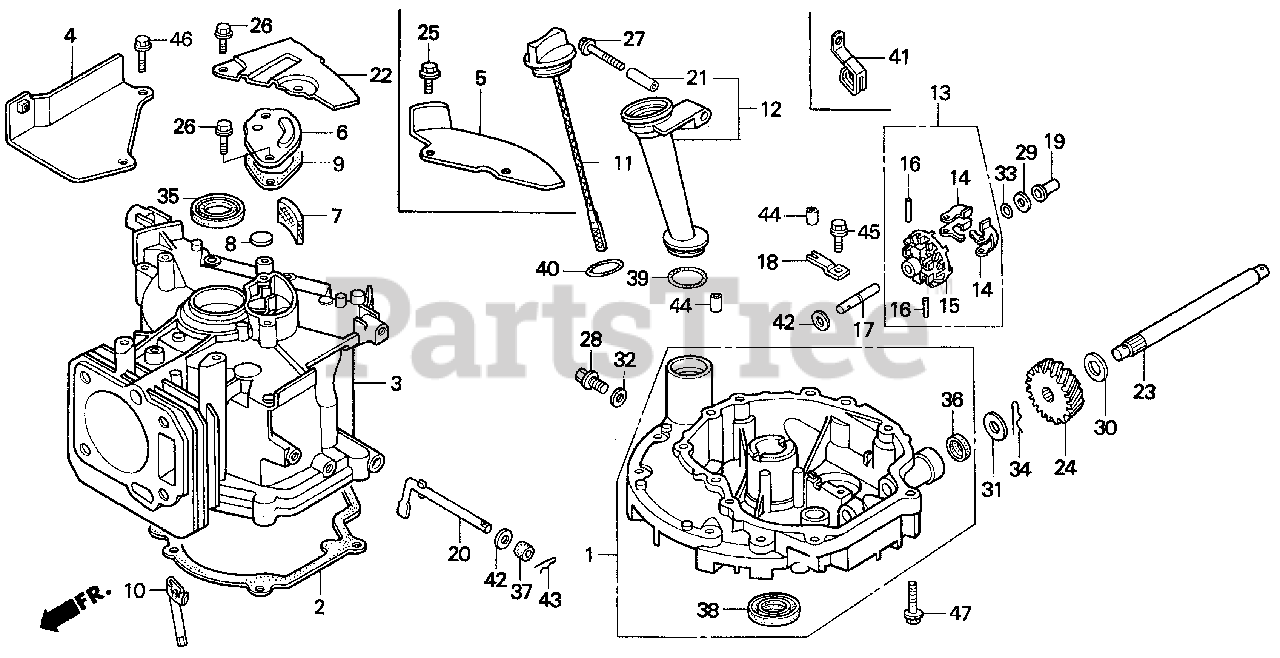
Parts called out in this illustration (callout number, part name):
1	PAN ASSY., OIL (USA-PUSH)
2	GASKET, OIL PAN
3	CYLINDER
6	CAP, BREATHER CHAMBER
7	FILTER, BREATHER
8	VALVE, BREATHER
9	GASKET, BREATHER CHAMBER
10	PIPE, OIL DEFENSE
11	DIPSTICK, OIL
12	EXTENSION, OIL FILLER
13	GOVERNOR ASSY.
14	WEIGHT, GOVERNOR
15	HOLDER, GOVERNOR WEIGHT
16	PIN, GOVERNOR WEIGHT
17	SHAFT, GOVERNOR HOLDER
18	PLATE, GOVERNOR SHAFT HOLDER
19	SLIDER, GOVERNOR
20	SHAFT, GOVERNOR ARM
21	COLLAR, EXTENSION
22	STAY, TANK
26	BOLT, FLANGE (6X14) (CT200)
27	BOLT, FLANGE (6X35) (CT200)
28	BOLT, DRAIN PLUG
29	WASHER, THRUST (6MM)
32	WASHER, DRAIN PLUG (10.2MM)
33	CLIP, GOVERNOR HOLDER
35	OIL SEAL (22X35X6)
37	OIL SEAL (6X11X4) (ARAI)
38	OIL SEAL (25X38X7)
38	OIL SEAL (25X38X7) (ARAI)
39	O-RING (22.5X2.2)
40	O-RING (26X2.7)
42	WASHER, PLAIN (6MM)
43	PIN, LOCK (8MM)
44	PIN, DOWEL (8X14)
45	BOLT, FLANGE (6X12)
47	BOLT, FLANGE (6X28)
NI	GOVERNOR KIT
